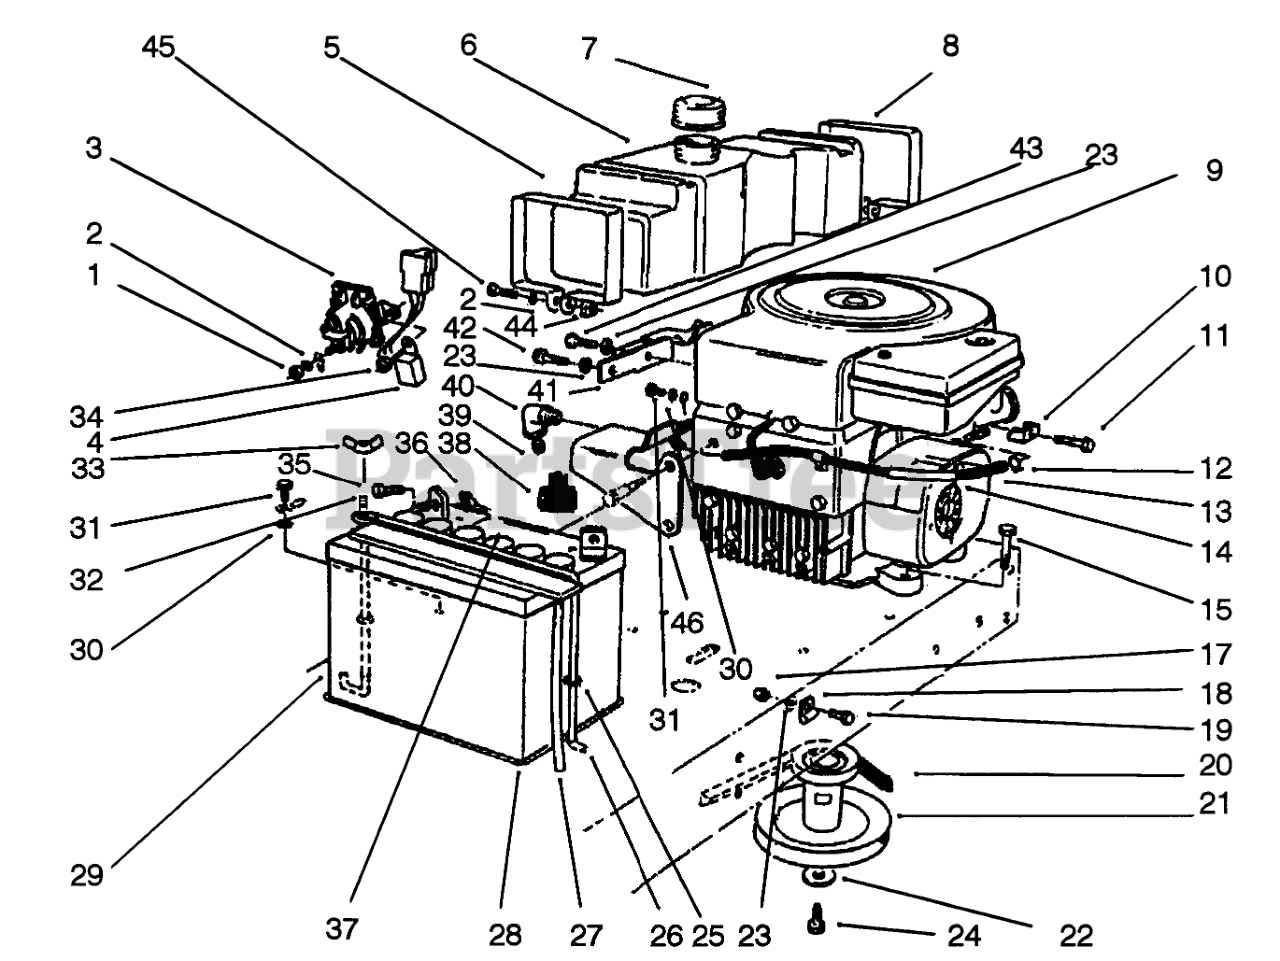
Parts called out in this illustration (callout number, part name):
1	NUT-JAM
2	WASHER-LOCK
3	SOLENOID
4	Module Interlock
5	Retainer-Front
6	TANK-5 QT GAS
7	GAS CAP ASM
8	Retainer-Rear
10	CLAMP-CASING
11	SCREW W ENGINE
12	CLAMP-HOSE
13	HOSE-FUEL
14	SUPPORT-FUEL LINE
15	SCREW-HH
17	NUT-LOCK, NI
18	CLAMP
19	SCREW-HH
20	V-BELT, TRACTION
21	ENGINE PULLEY ASM
22	WASHER-FLAT
23	WASHER-PLAIN
24	SCREW-HH
25	O-RING
26	HOLDDOWN-BATTERY
27	TUBE-BATT DRAIN/80-2600
28	PAD-SKID, ANTI
29	Battery
30	WASHER-LOCK, INTERNAL
31	SCREW-HWHTF
32	POST-BATTERY
33	NUT-WING
34	NUT-LOCK, NI
35	SCREW-HH
36	NUT-WING
37	CAP-BATTERY
38	BOOT-TERMINAL
39	3/8 PIPE PLUG
40	ELBOW-STREET, 90 DEG
41	REAR TANK MTG BRKT B
42	SCREW-HH
43	SCREW-HH
44	NUT-SQUARE
45	SCREW-HSH
46	FRT TANK MTG BRKT B
